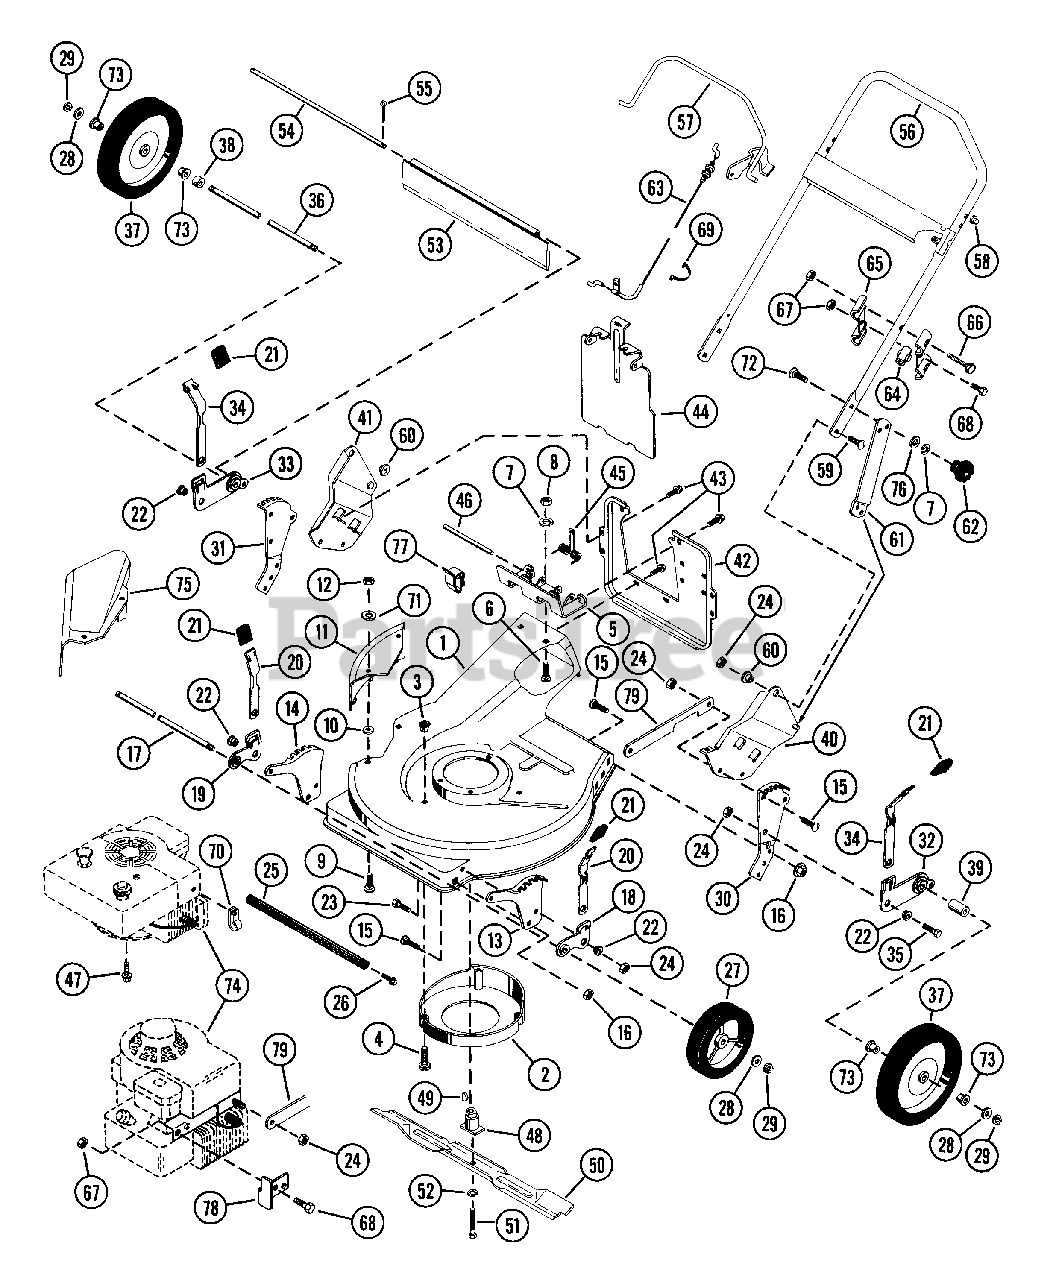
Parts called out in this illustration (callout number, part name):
1	21 INCH MOWER PAN W/DECALS
2	CENTER BAFFLE
3	PLASTIC GROMMET
4	SCR-TAP 10-16X.62 SLPH PL AB
5	HINGE PLATE
6	BLT-RDHDSQNK .312-18X.62SHTPL
7	WSHR-LK .312X.097 PL HVY
8	NUT-HEX .312-18
9	BLT-RDHDSQNK .31-18X.75 SHT PL
10	NUT-PUSH .312
11	SIDE DISCHARGE COVER
12	NUT-LK-NYL.312-18 PL
13	LEFT FRONT QUADRANT
14	RIGHT FRONT QUADRANT
15	BLT-RDHDSQNK .312-18X.62SHTPL
16	NUT-FLG. .312-18 PL
17	FRONT AXLE
18	LEFT ADJUSTOR BRACKET ASSEMBLY
19	RIGHT ADJUSTOR BRACKET ASSEMBL
20	FRONT HEIGHT ADJUSTMENT LEVER
22	BSHG-FLG .315X.500X.354X.875
23	BLT-HEX .31-18X.75 PL GR2
24	NUT-LK .312-18 GR A PL
26	BLT-SCRHFWH .38-16X.75 PL
27	T/WHL ASSY 7X1.50
28	WSHR-FL-STL .505X.880X.072 PL
29	RG-RTNG-EXT .438X.035
30	LEFT REAR QUADRANT
31	RIGHT REAR QUADRANT
32	REAR BRACKET AND BEARING ASSEM
33	REAR BRACKET AND BEARING ASSEM
34	HEIGHT ADJUSTMENT LEVER
35	BLT-HEX .31-18X.75 PL GR2
36	REAR AXLE-PUSH MOWER
37	WHL 10 IN O.D.
38	SPACER .75 X .51 X .50
39	TUBE .512 X .747 X 1.25
40	LH HANDLEBAR MTG BRACKET WELDM
41	RH HANDLEBAR MTG BRACKET WELDM
42	CATCHER MOUNTING PLATE
43	SCR-TAP 10-24X.375 HWH PL TR
44	DISCHARGE COVER
45	SG-TORS .090X.550X2.88
46	HINGE PIN
47	SCREW - FLG WIZ LOCK HH PL
48	BLADE ADAPTER
49	KEY-WDRF .156X.625X.25 SAE 6
50	21" MOWER BLADE
51	BLT-HEX .38-24X2.00 PL GR5
52	WSHR-LK .375X.094 MED PL
53	REAR PROTECTIVE GUARD
55	PIN-COTR .06X.50
56	HANDLE BAR ASSEMBLY
57	START BAIL - RECOIL
58	NUT-PUSH .312 DIA. PAL
59	BLT-RDHDSQNK .31-18X.75 GR5 PL
60	BSHG, FLG .325X.499X.26X.88
61	HANDLEBAR BRACKET
62	FLUTED WING
63	CABLE - ENGINE
63	ENGINE CABLE
64	PULL CORD RETAINER
65	BRACKET - ROPE GUIDE
66	BLT-HEX .25-20X1.50 PL GR5
67	NUT-LK-CTR .250-20 PL
68	BLT-HEX .25-20X.50 PL GR2
69	CABLE RETAINER
70	CLIP
71	WSHR-FL-STL .38X.875X.083 PL
72	BLT-RDHDSQNK .31-18X1.25 SHTPL
73	BSHG-FLG .500X.625X.500X.750
74	ENGINE
75	DISCHARGE CHUTE
76	WSHR-FL-STL .323X.625X.062 PL
77	CLIP-HARNESS TINNERMAN
78	LEVER GUARD
79	ANTIVIBRATION STRAP
